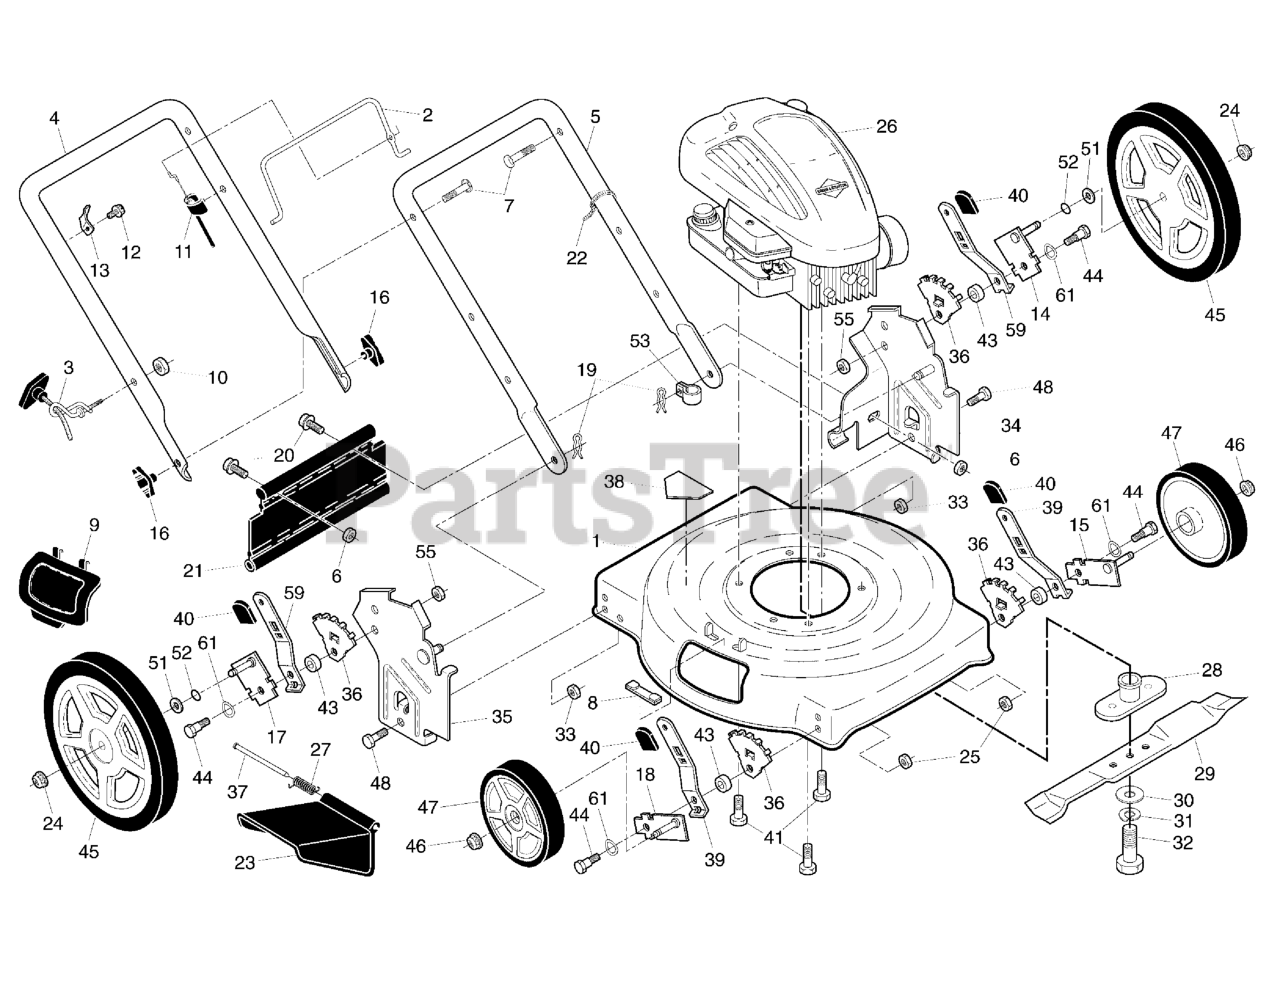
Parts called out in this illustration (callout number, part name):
1	Lawn Mower Housing (Includes Key Number 38)
2	Control Bar
3	Rope Guide
4	Upper Handle
5	Lower Handle
6	Locknut, Hex 1/4-20
7	Handle Bolt 5/16-18
8	Clip, Closeout
9	Mulcher Plate
10	Nut, Hex 1/4-20
11	Engine Zone Control Cable
12	Hex Washer Head Screw #10-24 x 1/2
13	Up-Stop Bracket
14	Axle Arm Assembly, Rear, LH
15	Axle Arm Assembly, Front, LH
16	Handle Knob
17	Axle Arm Assembly, Rear, RH
18	Axle Arm Assembly, Front, RH
19	Hairpin Cotter
20	Screw, Hex Cap Head 1/4-20
21	Rear Defl ector
22	Wire Tie
23	Discharge Guard
24	Nut, Hex, Flangelock 3/8-16
25	Nut, Hex, Flangelock 5/16-18
26	* ENGINE, Briggs & Stratton
27	Torsion Spring
28	Blade Adapter
29	22" Blade
30	Hardened Washer
31	Helical Lockwasher 3/8
32	Screw, Hex Head, Grade 8, 3/8-24 x 1-3/8
33	Nut, Hex, Nylock 5/16-18
34	Wheel Bracket Support, LH
35	Wheel Bracket Support, RH
36	Wheel Bracket Adjuster
37	Hinge Rod
38	Danger Decal
39	Selector Spring, Front
40	Selector Knob
41	Screw, Hex Head, Threaded, Rolled 3/8-16 x 1
43	Spacer
44	Shoulder Bolt 5/16-18
45	Wheel & Tire Assembly, Rear, 12"
46	Nut, Hex, Flangelock 3/8-16
47	Wheel & Tire Assembly, Front, 8"
48	Bolt, Hex Head 5/16-18
51	Washer, Flat 3/8
52	O-Ring
53	Clip, Cable
55	Nut, Hex
59	Selector Spring, Rear
61	Washer, Curved, Cylindrical
